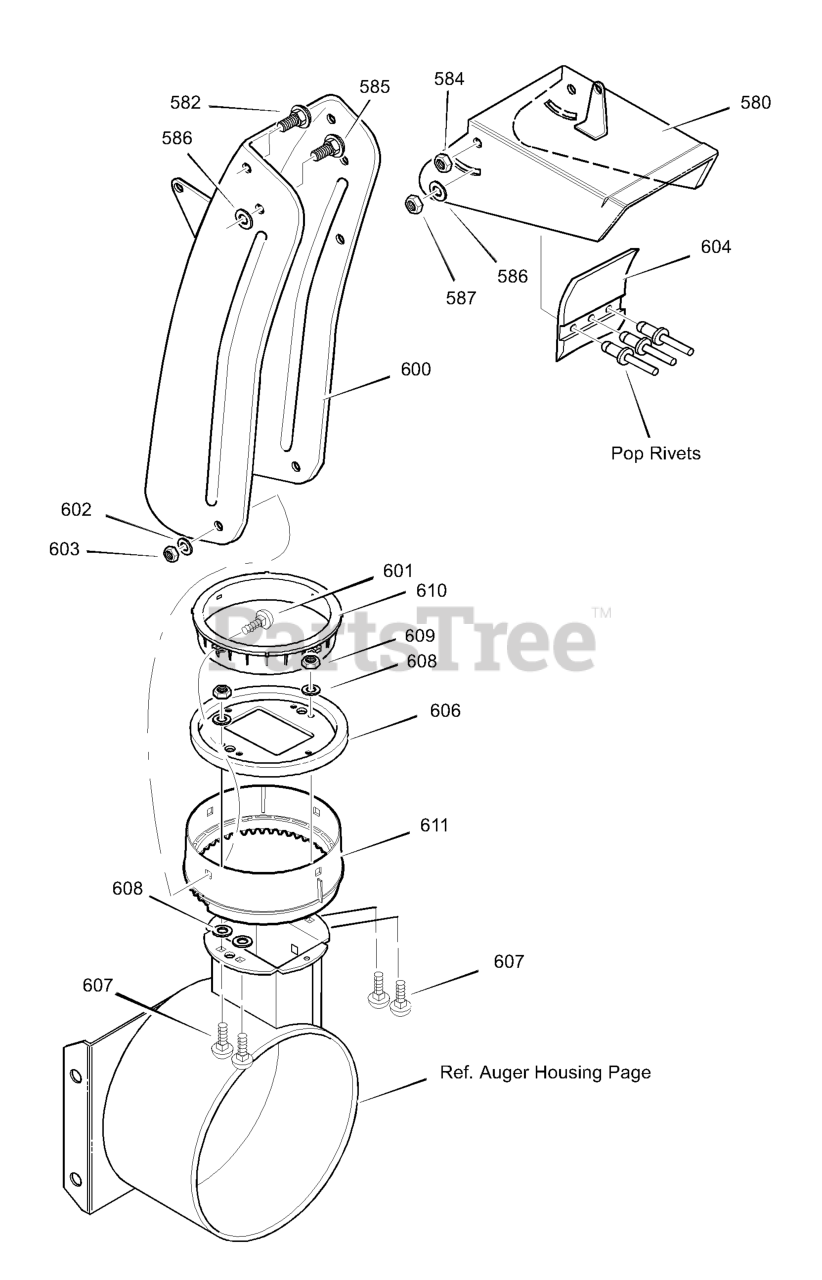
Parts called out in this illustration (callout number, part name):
580	CHUTE, UPPER W/REMOTE
582	SCREW, 5/16-18 x 0.75
584	NUT, 5/16-18
585	SCREW, 5/16-18 x 0.75
586	PLASTIC WASHER
587	NUT, 5/16-18
600	CHUTE, LOWER W/GUARD
601	BOLT, 5/16-189 X 1.00
602	WASHER, FLAT
603	NUT
606	CHUTE COLLAR
607	BOLT
608	WASHER, FLAT
609	NUT, 1/4-20 NYLOCK
610	RETAINER, RING INNER
611	RETAINER, RING OUTER
